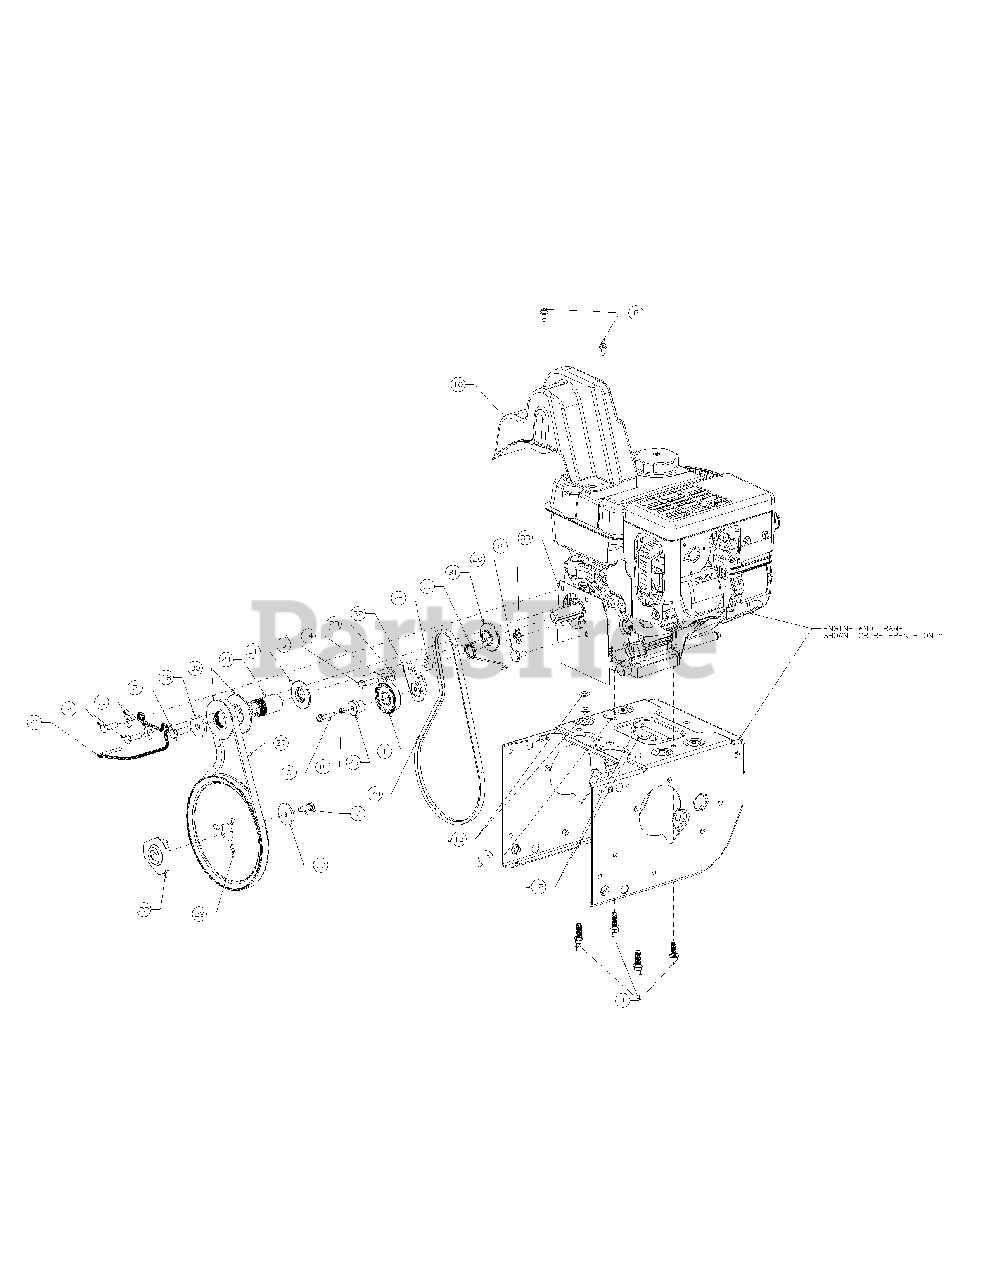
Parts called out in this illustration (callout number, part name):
1	Pulley Asm:Idler
2	Hhcs-5/16-24 X 1.0
3	Screw 3/8-24X1.25
4	Screw-Hex
5	Screw-Hex 5/16-24
6	Screw-Hex 1/4-20 X
7	Screw-Hex Cap 5/1
8	Screw Hex.Wash.Hd
9	Nut-Push On
10	Cover:Belt
11	Spring-Torsion
12	Plug-3/8 Dia Id X
13	Plug-1/2 Id X 3/32
14	Washer-Lock 5/16
15	Washer-Fl
16	Washer-Lock
17	Washer-Fl
18	Washer-Flat .45 X
19	Grease
20	Screw-Shoulder
21	Guide-Belt
22	Pulley-Adapter .75
23	Spacer-Shoulder
24	Spacer-Pulley
25	Spacer-Idler Brkt
26	Spacer:Shoulder
27	Belt-V Type
28	Belt-V Type 3L
29	Pulley-Auger 8.1 O
30	Pulley-Half 4L V
31	Pulley Half-3/8 V
32	Bracket-Idler Drive
33	Plate-Cov
